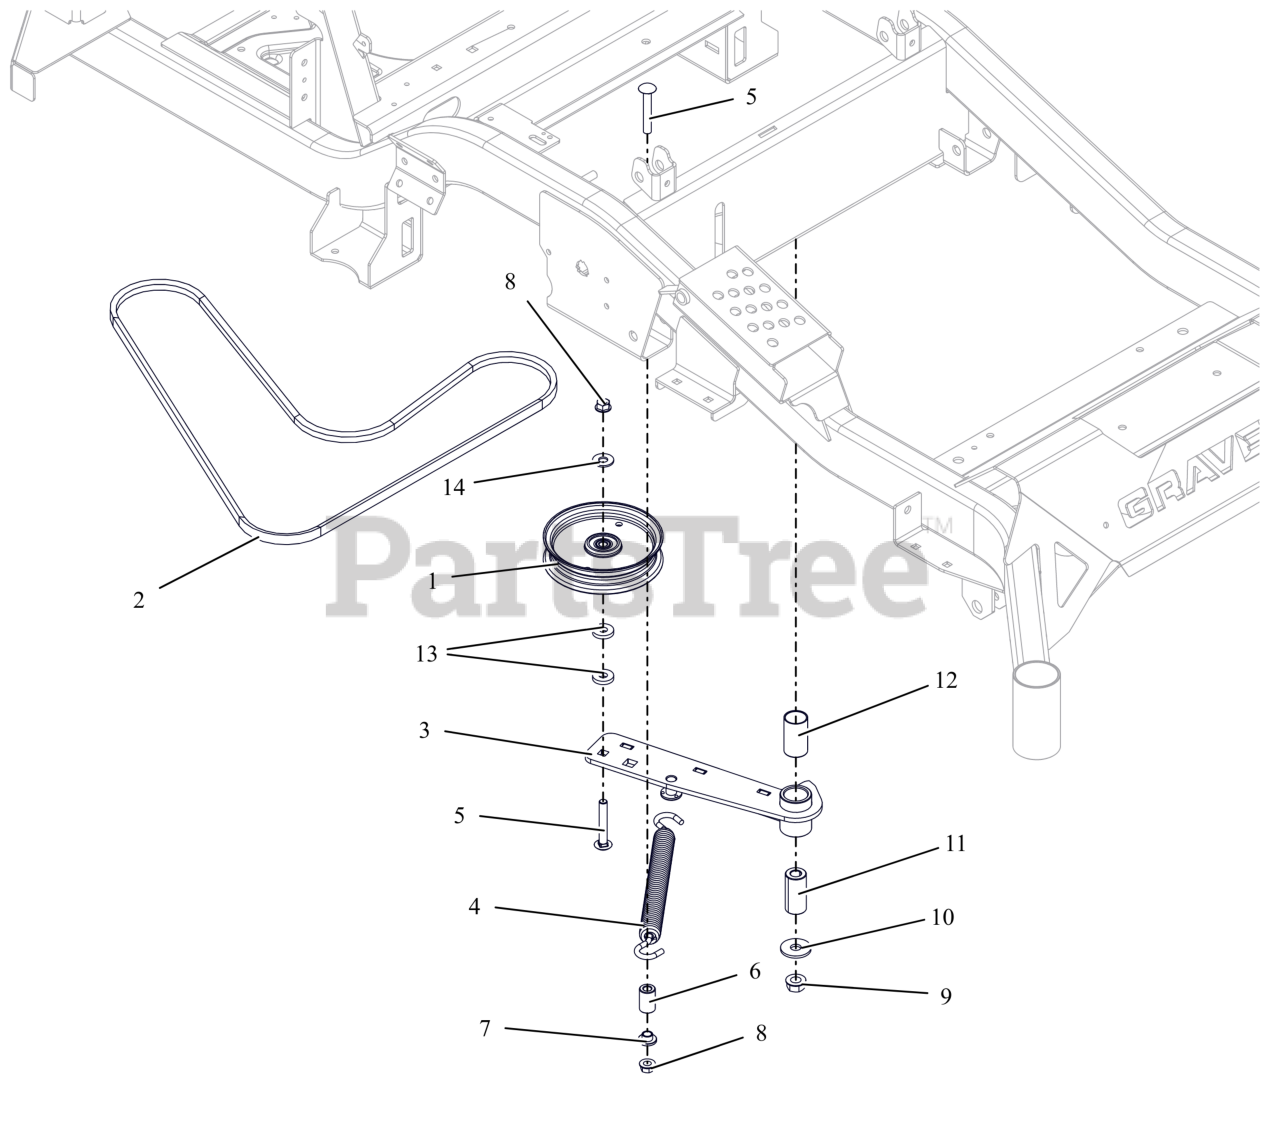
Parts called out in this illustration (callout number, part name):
1	IDLER- FLAT - 5.00" X .75"
2	V-BELT, 4L-WRAPPED
3	WLDMT, HYDRO DRIVE IDLER ARM (BLACK)
4	SPRING, EXTENSION
5	BLT, RHSSN.38-16X2.50 G5 ZCC
6	BUSHING, SLV .380X.750X1.190
7	BSHG-FLG .385X.500X.875X.406
8	NUT-LK-TOP-FLG .38-16 ZC120
9	NUT-LK-TOP-FLG .500-13 GF ZCC
10	WSHR-FL-STL.511X1.44X.125ZC120
11	BSHG, SPCR .502X.997X2.03 PM
12	BSHG, 1.00X1.125X1.937
13	WSHR, FLT .406X1.00X.188 ZCC
14	WSHR,FLT .438X1.00X.083 ZCC
